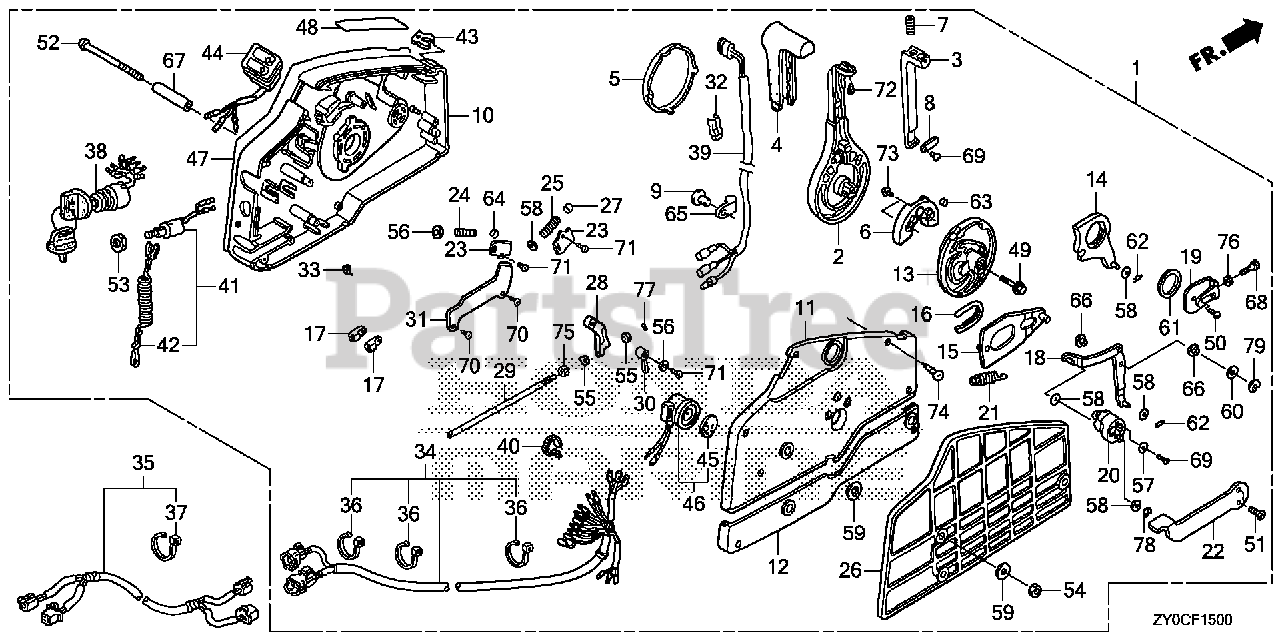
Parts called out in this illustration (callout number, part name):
1	S/R SW 2 LIGH POW TL
1	BOX ASSY., REMOTE CONTROL (HI-LEX)(PT)
2	HANDLE, REMOTE CONTROL
3	LEVER, HANDLE LOCK
4	GRIP, REMOTE CONTROL HANDLE
5	CAP, HANDLE
6	BLOCK, NEUTRAL LOCK
7	SPRING, REMOTE CONTROL HANDLE
8	PLATE, LEVER SETTING
9	CLAMP, HARNESS
10	HOUSING, REMOTE CONTROL BOX (A)
11	HOUSING, REMOTE CONTROL BOX (B)
12	HOUSING, REMOTE CONTROL BOX (C )
13	WHEEL, CONTROL
14	ARM, SHIFT LINK
15	PLATE, SLIDING
16	COLLAR, SLIDING PLATE
17	PIVOT, SHIFT
18	ARM, LINK JOINT
19	BRACKET, LINK JOINT
20	WHEEL, ACCELERATOR
21	SPRING, ACCELERATOR WHEEL
22	LEVER, IDLE
23	PLATE, SPRING SETTING
24	SPRING, SHIFT CLICK
25	SPRING, CHOKE RETURN
26	SPACER, REMOTE CONTROL BOX
27	SPACER, CLICK SPRING
28	BLOCK, THROTTLE FRICTION
29	BOLT, FRICTION
30	SPACER, NEUTRAL SWITCH
31	CLAMP, POWER TILT CORD
32	PIPE, HARNESS GUIDE
33	SPACER, CABLE CLAMP
34	CABLE ASSY. B, REMOTE CONTROL (4P+6P)
35	CABLE ASSY., REMOTE CONTROL EXTENSION (4P+6P)
36	TIE, CABLE (NATURAL 2.4X92) Use up to Frame SN 1300359.
37	TIE, CABLE (NATURAL 2.4X92) Use up to Frame SN 1300359.
38	SWITCH ASSY., COMBINATION (SINGLE) (DUAL)
39	SWITCH ASSY., POWER TRIM-TILT
40	BAND (BLACK 3.5X140)
41	SWITCH ASSY., EMERGENCY STOP
42	WIRE, EMERGENCY (SINGLE) (DUAL)
43	CLIP, EMERGENCY LOCK
44	LAMP ASSY., INDICATOR
45	PLATE, TURN SIGNAL BUZZER DUAL QTY = (2) (SINGLE)
46	BUZZER, WARNING DUAL QTY = (2) (SINGLE)
47	PLATE, REMOTE CONTROL (COUTION COLOR=RED & YELLOW)
48	MARK, FAST IDLE
49	BOLT, FLANGE (8X35) Use from Frame SN 4800713.
50	SCREW, PAN (6X10)
51	SCREW, FLAT (5X12) Use from Frame SN 4800713.
52	SCREW (6X95)
53	NUT, HEX. (16MM) DUAL QTY = (2) (SINGLE)
54	NUT, HEX. (6MM)
55	WASHER, PLAIN (4MM) Use from Frame SN 4800713.
56	WASHER, PLAIN (5MM)
57	WASHER, PLAIN (5MM)
58	WASHER, PLAIN (6MM) Use from Frame SN 4800713.
59	WASHER (6MM)
60	WASHER, PLAIN (8MM) Use from Frame SN 4800713.
61	WASHER (28MM)
62	PIN, LOCK (6MM)
63	PIN (6X6)
64	ROLLER, CLICK
65	CLIP, WIRE HARNESS (6.3MM)
66	COLLAR, LINK JOINT
67	COLLAR, DISTANCE (6X10X43.5)
68	BOLT, HEX. (5X16)
69	SCREW, PAN (5X10)
70	SCREW, TAPPING (5X8) (FOR SILVER MUFFLER)
71	SCREW, TAPPING (5X10)
72	SCREW, TAPPING (5X12)
73	SCREW, TAPPING (6X16)
74	SCREW, TAPPING (5X25)
75	NUT, HEX. (6MM)
76	NUT, HEX. (5MM)
77	E-RING (3MM)
78	E-RING (4MM)
79	E-RING (7MM)
